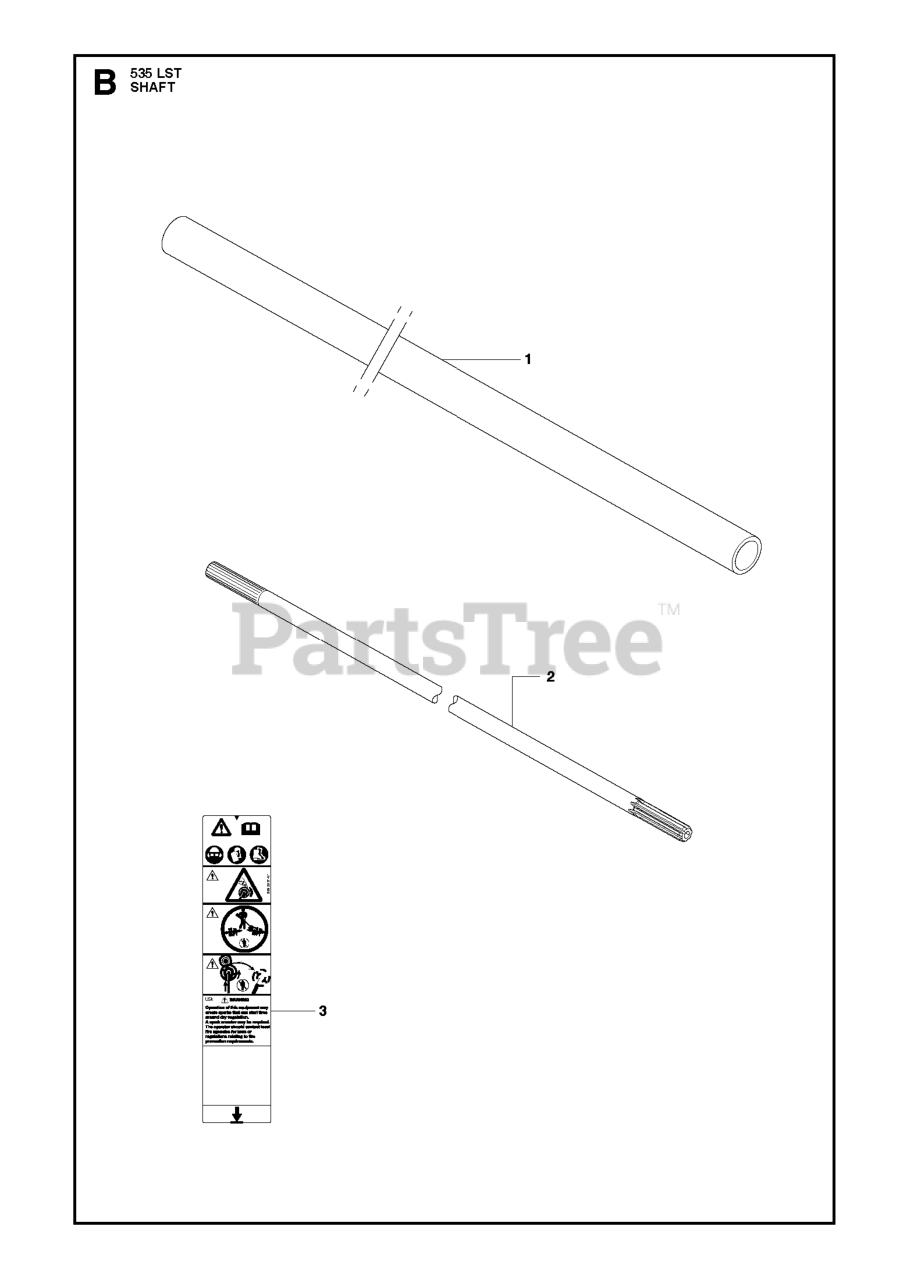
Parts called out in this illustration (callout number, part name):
1	DRIVE TUBE ASSEMBLY
1	FRAME RAIL RH
2	DRIVESHAFT
2	DRAWBAR, GT
3	LABEL WARNING TRIMMERS AND BRU
4	Nut, Lock Hex 7/16 Unc
5	DASH.STEALTH.YTGT.2CYL.BLK
6	DASH VGT, LOWER
7	SCREW
8	SUPPORT, BATTERY
14	HOOD ASM.
15	LENS LH
16	COVER ACCESS
17	SCREW 3/8-16X3/4
18	GRILLE
19	WASHER
20	BOLT
24	FOOTREST PNT RH
25	LENS RH
28	FOOTREST PNT LH
30	SADDLE.HYDRO.95
31	BRACKET SUPT 1-PC VGT STEERING
34	PLATE ASM ENG CHASSIS
35	WASHER
36	SCREW 5/16"
37	FENDER, PNT
39	BRACKET AXLE, FRONT
43	FRONT SUSPENSION BRKT LH
44	FRONT SUSPENSION BRKT RH
45	BRACKET, ASM., SUSP CHASSIS RH
50	BRACKET, CHASSIS FRONT
56	BRACKET ASM., SUSP CHASSIS LH
58	BRACKET ASM., FENDER
60	SCREW.3/8-16
68	Screw 5/16-18 x 1/2 Hex, Self Tapping 5/16-18 x 1/2
86	BOLT
91	FRAME RAIL LH
99	ROD ASM, BYPASS
115	BUMPER ASM.
116	BUMPER BRACKET
117	PLUG PLASTIC
122	SCREW.HEX.WS.HD.8-18 X 7/8
130	SCREW
137	BOLT
138	CUPHOLDER
139	BOLT, SHOULDER 5/16-18
140	MAGNET STEALTH
141	STRIKER PLATE
142	BRACKET DASH STEALTH(R)
143	SKIRT GRILLE RH
144	BRACKET DASH STEALTH LH
146	SKIRT GRILLE LH
148	EXTRUSION BUMPER (3 2) (2 2)
150	DUCT HEAT HOOD
152	BROWNING SHIELD
153	LIGHT ASM.
156	SCREW
158	SCREW 3/8-16X1/2
160	SCREW 5/16-18X1/2"
161	CONSOL.FUEL.WINDOW.BLACK
162	SCREW.HI-LO.CONSOLE
165	Bracket Support Fuel Tank
166	Nut, Crownlock Hex 7/16-14 unc
